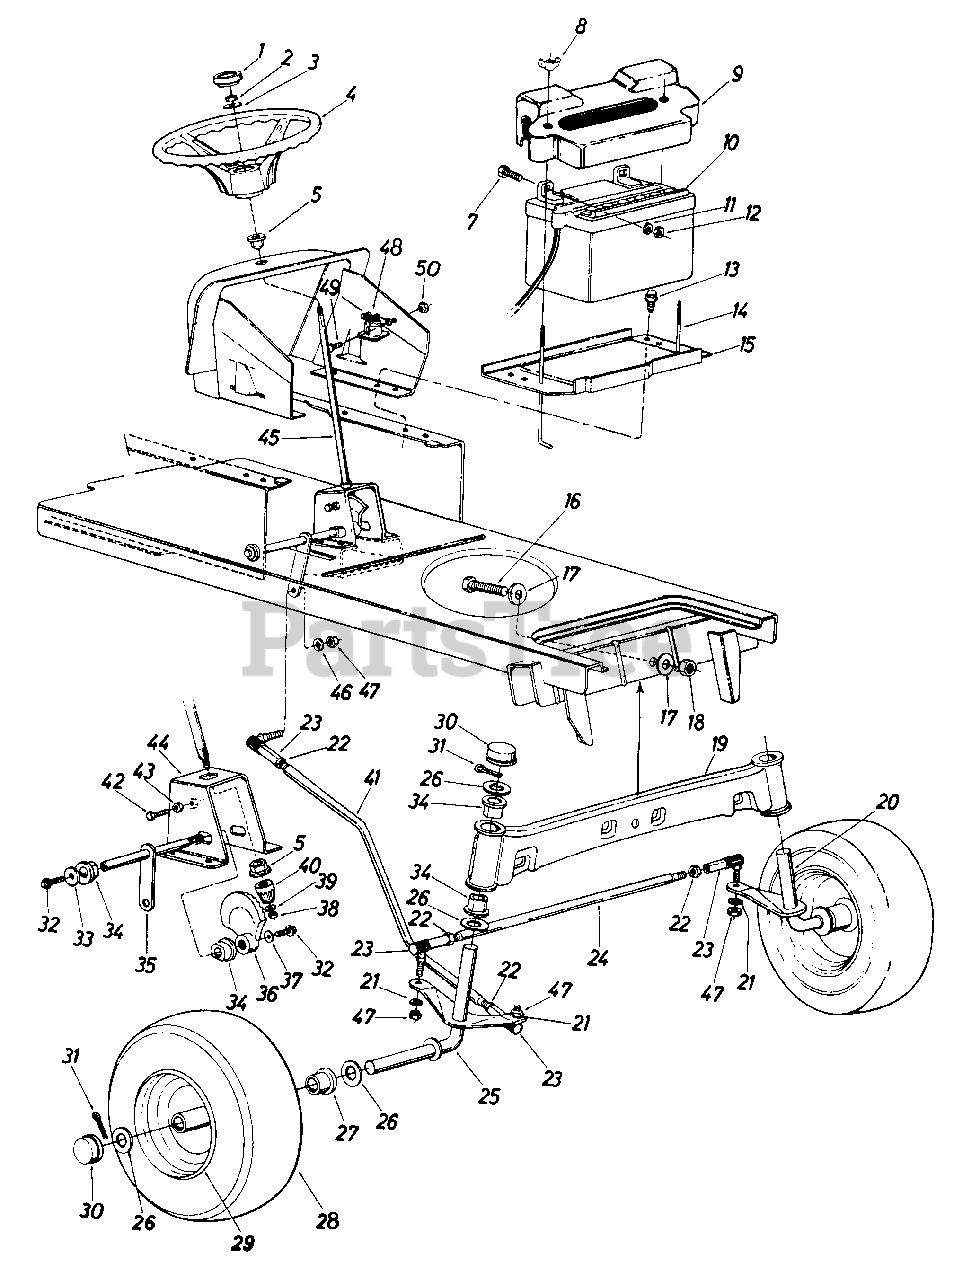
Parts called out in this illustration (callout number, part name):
1	Steering Wheel Cap
2	Hex Cent. L-Nut 5/16-18 Thd.
2	Hex Cent. L-Nut 5/16-24 Thd.
3	Bell-Wash. 5/16" I.D. x .87" O.D. x .060
4	Steering Wheel
5	Plastic Hex Bearing 5/8" I.D.
7	Hex Scr. 1/4-20 x .62" Lg.
8	Wing Nut Plastic 1/4-20 Thd.
9	Battery Cover
10	12-V Battery
11	L-Wash. 1/4" Scr.
12	Hex Nut 1/4-20 Thd.*
13	Hex Thd. Rolling Scr. 1/4-20 x.50" Lg.
14	Battery Hold Down Rod
15	Battery Plate
16	Hex Scr. 5/8-18 x 2.50" Lg.
17	Flat Wash. .66" I.D. x 2.25" O.D. x .17
18	Hex Cent. L-Nut 5/8-18 Thd.
19	Front Pivot Bar Ass'y.
20	Front Axle Ass'y. L. H .
21	L-Wash. 3/8" Scr.
22	Hex Jam Nut 3/8-24 Thd.
23	Ball Joint Ass'y.
24	Tie Rod
25	Front Axle Ass'y. R.H.
26	Fl-Wash. .780 I.D. x 1.59 O.D.
27	Flange Bearing
28	Front Wheel Ass'y. Comp.
29	Front Wheel Rim Only
29	Air Valve
29	Grease Fitting
30	Dust Cover
31	Cotter Pin 5/32" Dia. x 1.00" Lg.
32	Hex Scr. 3/8-24 x .75" Lg. Grade 5
33	Fl-Wash. 3/8 I.D. x 1.25 O.D. x .090
34	Flange Double "D" Brg. .753 I .D.
35	Steering Arm Shaft Ass'y.
36	Side Gear Steering
37	Bell-Wash. 3/8" I.D.
38	Hex Cent. L-Nut 5/16-24 Thd.
39	Fl-Wash. 5/16" I.D. x .62 O.D. x .059
40	Pinion Gear Steering
41	Drag Link
42	Hex Nylon Scr. 3/8-16 x 1.25"
43	Hex Nut 3/8-16 Thd.
44	Steering Gear Sup. Ass'y.
45	Steering Shaft
46	L-Wash. 3/8" Scr.
47	Hex Nut 3/8-24 Thd.
48	Solenoid
49	Hex Bolt 1/4-20 x .50" Lg.
50	Hex Sems Nut 1/4-20 Thd.
